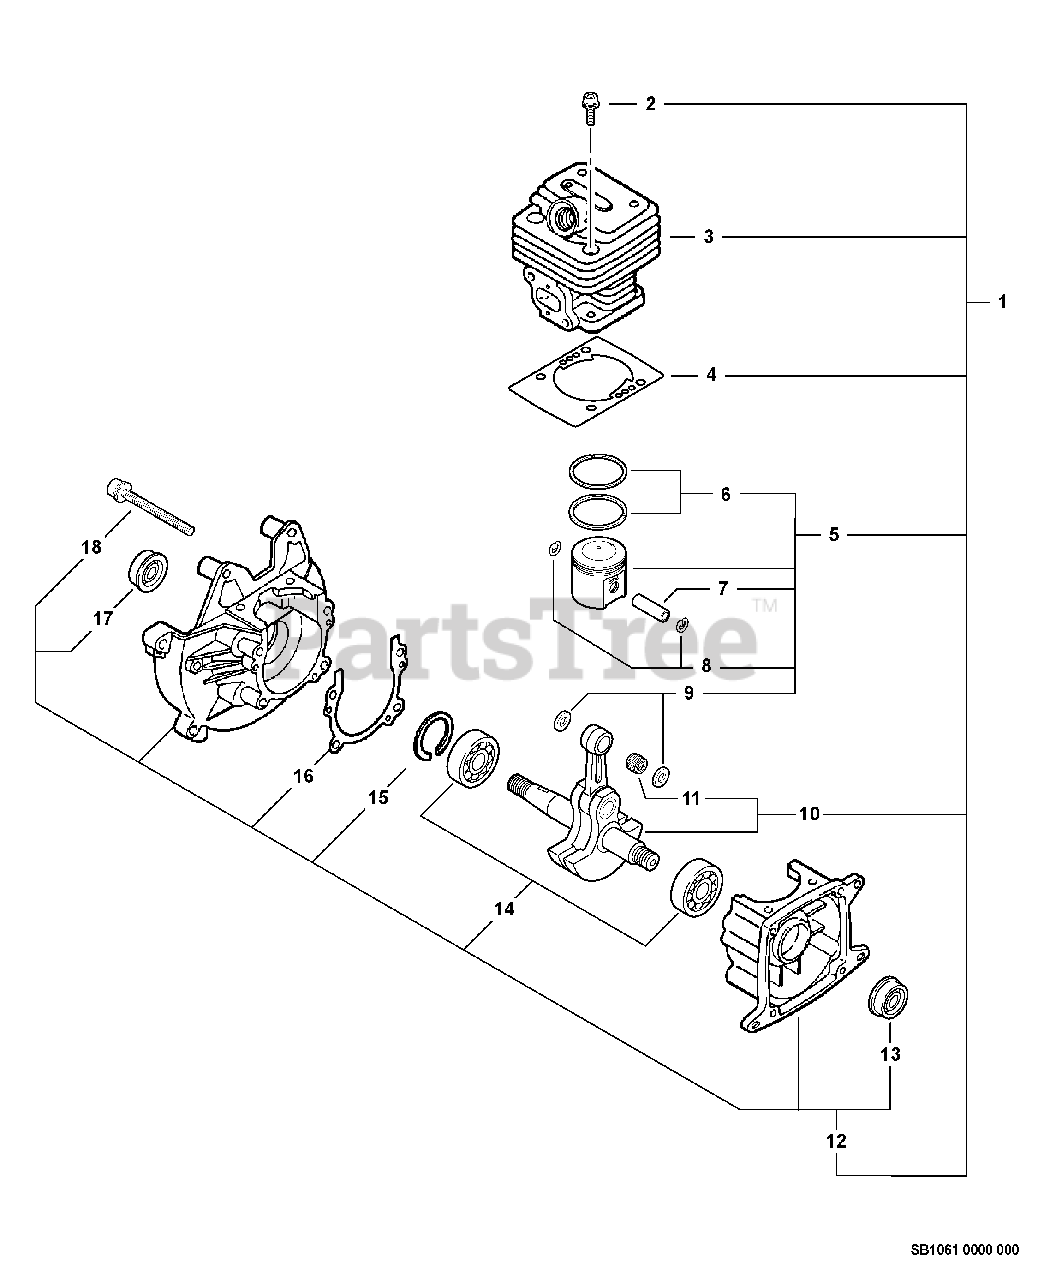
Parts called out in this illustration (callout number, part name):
1	SHORT BLOCK -- SB1062
2	SCREW - 5X22
3	CYLINDER
4	GASKET, CYLINDER
5	PISTON KIT
6	RING, PISTON
7	PIN, PISTON
8	RING, RETAINING
9	SPACER, PISTON
10	CRANKSHAFT ASSY
11	BEARING, NEEDLE - 8
12	CRANKCASE KIT
13	SEAL, OIL
14	BEARING, BALL - 6001C3
15	RING, RETAINING - 28
16	GASKET, CRANKCASE
17	SCREW - 5X25
18	SEAL, OIL - 12
